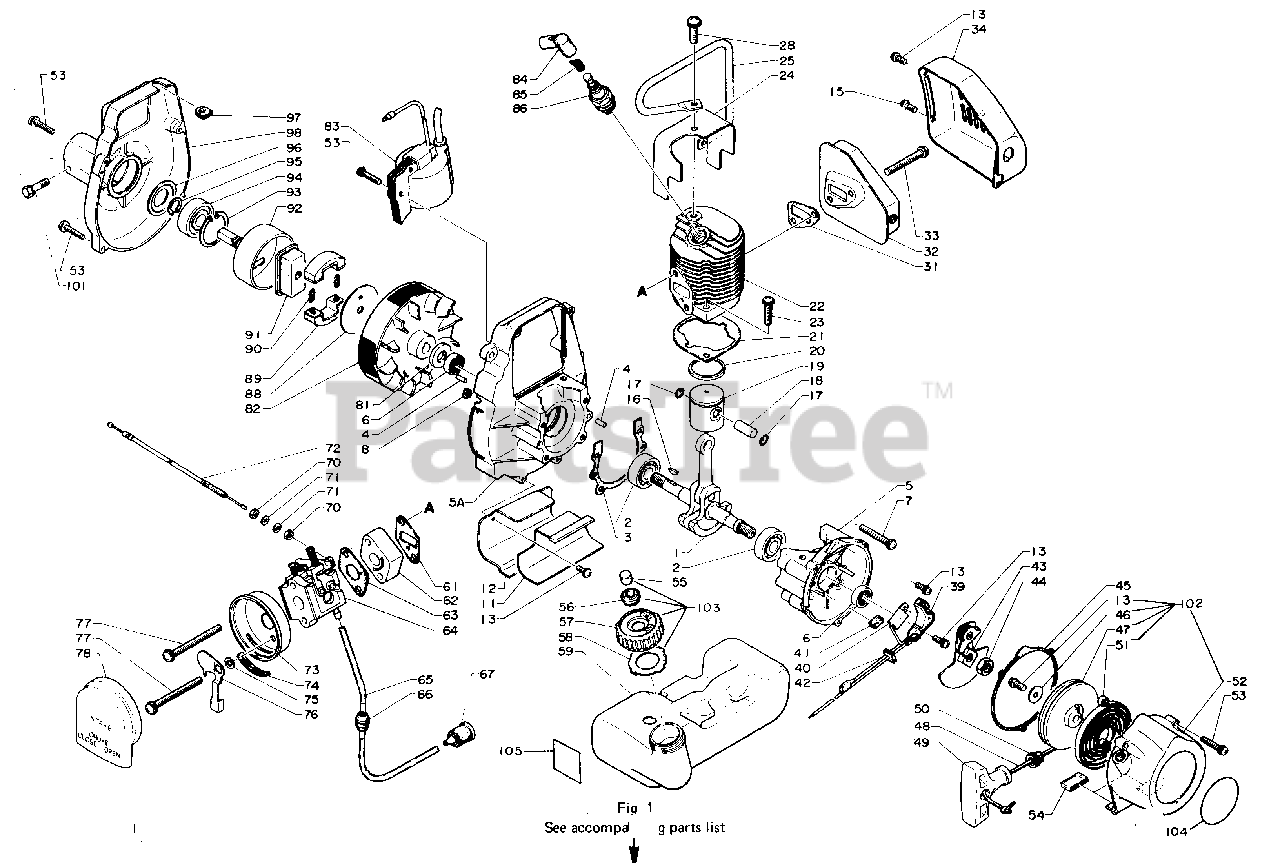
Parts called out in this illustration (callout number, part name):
1	Crankshaft assembly
2	Ball bearing 6200
3	Gasket - crankcase
4	Knock pin
5	Crankcase set
6	Oil seal
7	Screw 5 x 30 w/W, SW
11	Cushion - fuel tank
13	Screw 4 x 10 w/W, SW
15	Screw 4 x 14 w/W, SW
16	Woodruff key
17	Circlip - piston pin
18	Piston pin
20	Piston ring
21	Gasket - cylinder base
22	Cylinder
23	Screw 6 x 22 w/W, SW
24	Cylinder cover
28	Screw 5 x 14 w/W, SW
31	Gasket - muffler
33	Screw 5 x 40 w/W, SW
34	Muffler cover
39	Breaker point set
40	Condenser
43	Ratchet assembly
45	Gasket - starter case
47	Recoil drum
48	Starter rope
49	Starter handle
50	Rope guide
51	Rewind spring
52	Starter case
53	Screw 4 x 20 w/W, SW
54	Cushion - fuel tank
55	Filter - check valve
56	Check valve
57	Cap - fuel tank
58	Gasket - fuel tank cap
59	Fuel tank
62	Insulator
64	Carburetor assembly
65	Fuel pipe
66	Grommet - fuel pipe
67	Fuel strainer
71	Washer 6
72	Throttle cable
73	Case - air cleaner
76	Choke shutter
77	Screw 5 x 57 w/W, SW
78	Air filter
82	Flywheel
83	Ignition coil
84	Cap - spark plug
85	Coil spring - plug cap
86	Spark plug
88	Side plate
89	Clutch plate
90	Clutch spring
91	Clutch boss
92	Clutch drum
93	Circlip 32
94	Ball bearing 6201
95	Circlip 11
98	Fan cover
101	Bolt 5 x 20 w/W, SW
102	Recoil starter assembly, includes 13, 46, 47, 48, 49, 50, 51 & 52
103	Cap assembly - fuel tank includes 55, 56, 57 & 58
104	Decal starter housing
105	Decal starting instructions
